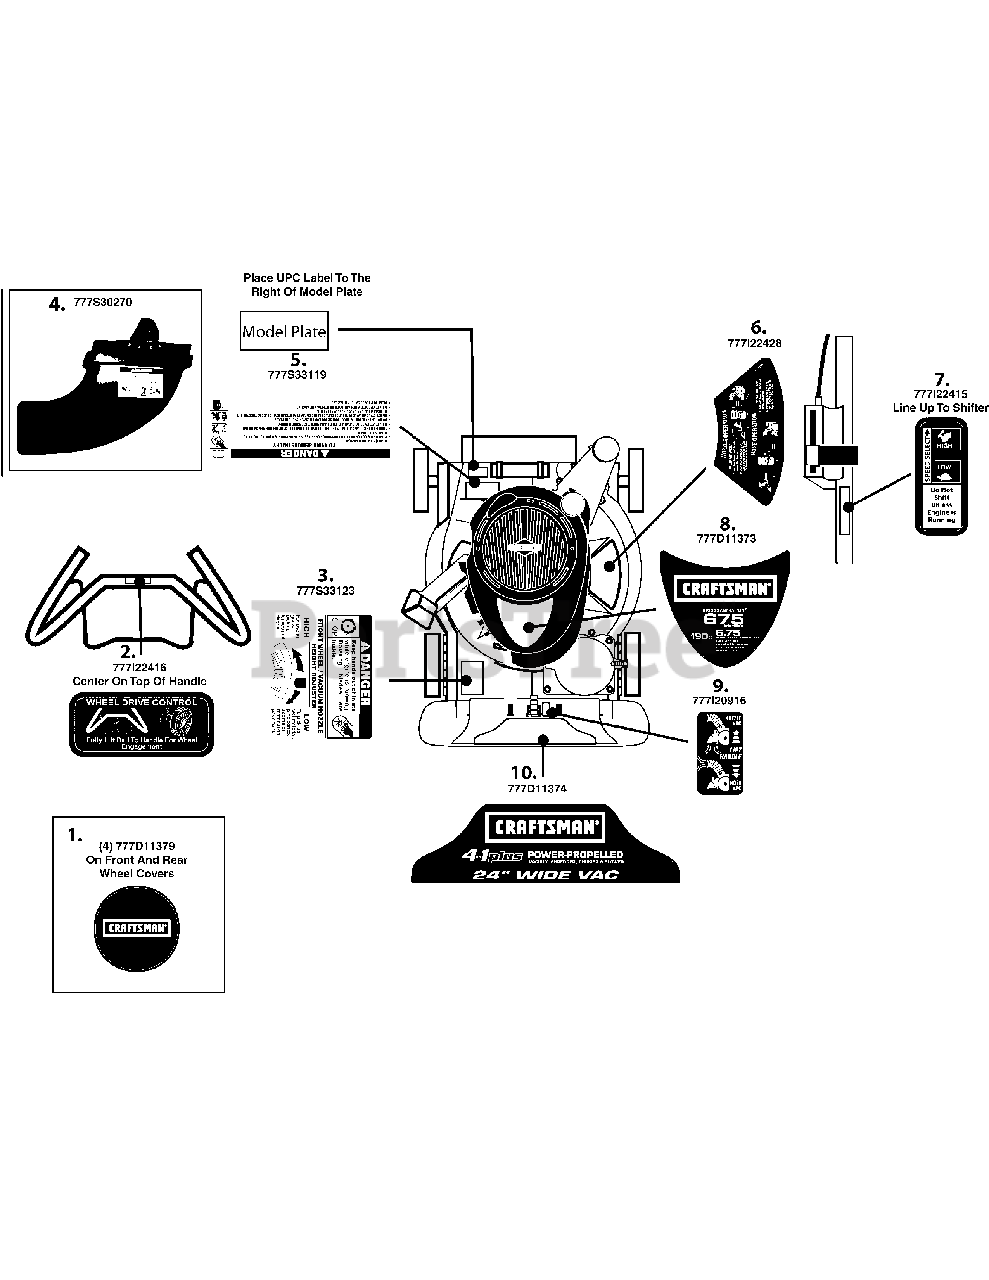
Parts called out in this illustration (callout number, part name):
1	LABEL-HUB CAP CRAFTSMAN
2	LABEL-HANDLE
3	LABEL-CSV BLADES DANGER
4	LABEL-DANGER
5	LABEL-CSV DANGER
6	LABEL-DECK
7	LABEL-HANDLE
8	LABEL-CHIPPER SHREDDER CRAFTSMAN
9	LABEL-DECK FRONT N
10	LABEL-NOZZLE CHIPPER SHREDDER
